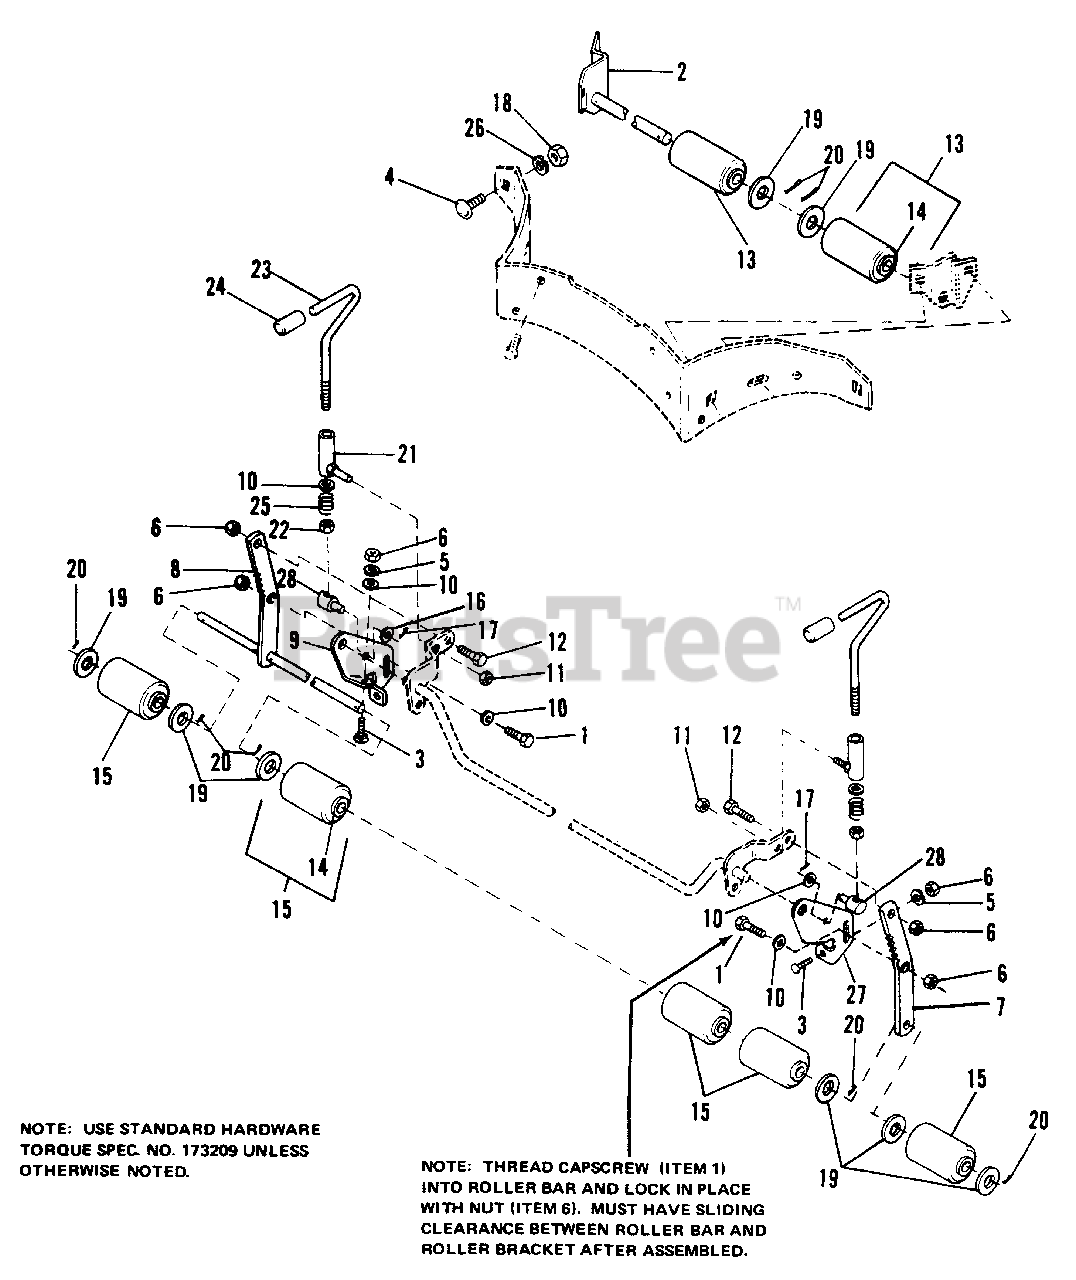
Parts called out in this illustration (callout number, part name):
1	CAPSCREW, Hex Hd., 3/8-16 x 1
2	BRACKET & SHAFT ASSY
3	BOLT, Carriage, 3/8-16 x 3/4
4	BOLT, Carriage, 5/16-18 x 3/4
5	LOCKWASHER, 3/8
6	NUT, Hex, Full, 3/8-16
7	BAR, Roller
8	SHAFT ASSY, Roller
9	BRACKET, Roller, R.H.
10	WASHER, Plain, 3/8
11	NUT, Hex, Full Lock, 3/8-16
12	CAPSCREW, Hex, Full Lock, 3/8-16 x 1
13	ROLLER SUB ASSY
15	ROLLER ASSY
16	WASHER, Plain, 5/16
17	PIN, Cotter, 3/22 x 5/8
18	NUT, Hex, Full, 5/16-18
19	WASHER, Plain, 5/8
20	PIN, Cotter, 3/16 x 1
21	SOCKET ASSY
22	NUT, Hex, Jam, 3/8-16
23	HANDLE, Adjusting
24	GRIP
26	LOCKWASHER, 5/16
27	BRACKET, Roller, L.H.
